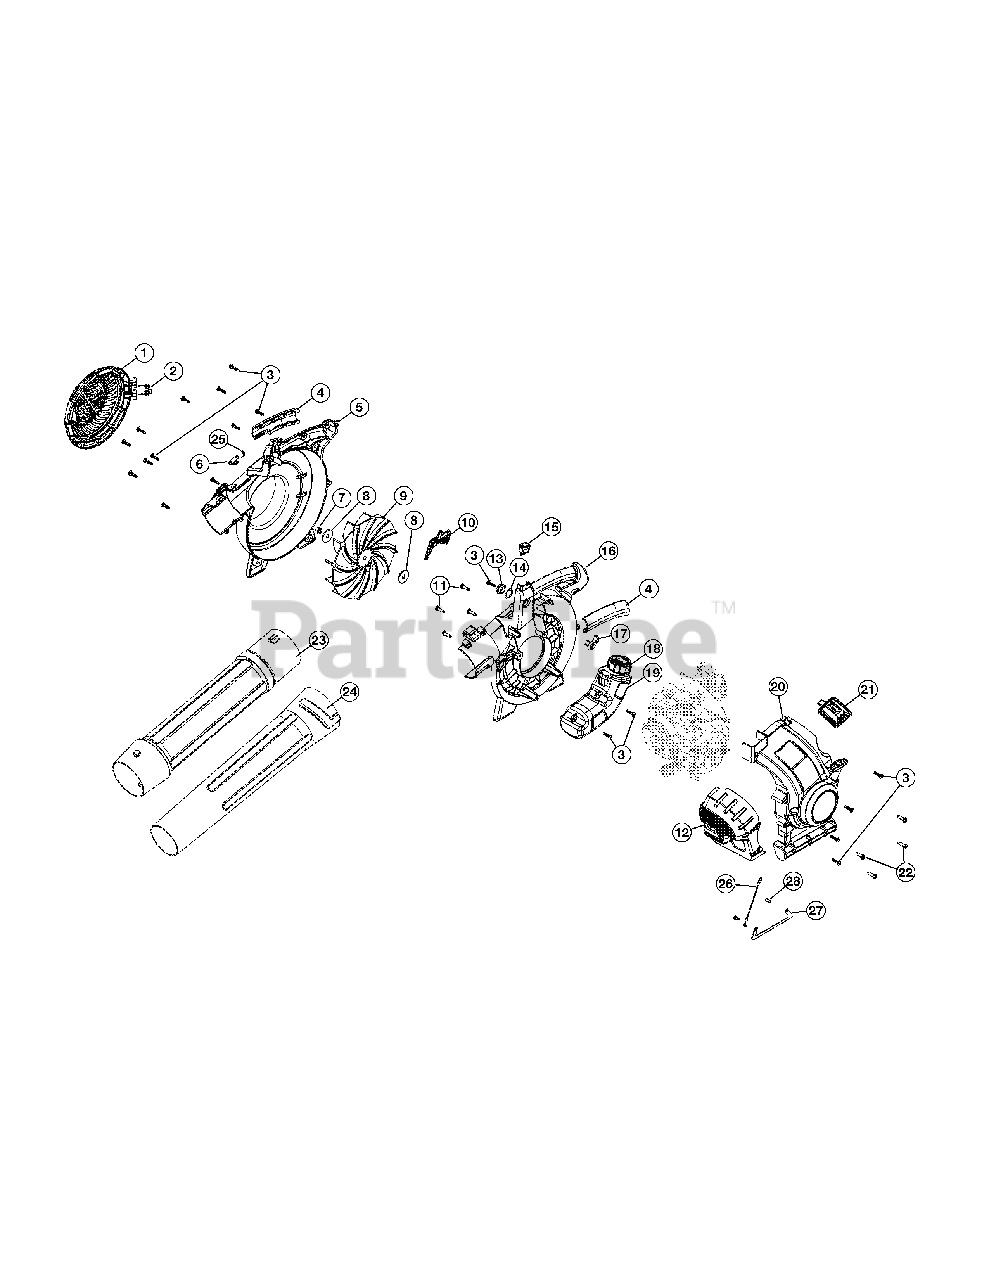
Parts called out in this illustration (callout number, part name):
1	Intake Cover
4	Handle Grips
5	Impeller Housing (Incl. Ref No. 4)
6	Latch Tube
10	Throttle Trigger
11	Screw
12	Muffler Cover (Incl. Ref No. 3)
13	Inner Trigger Lock
14	Wavey Washer
16	Impeller Housing (Incl. Ref No. 4)
17	Outer Trigger Lock
19	Fuel Tank Assembly (Incl. Ref No. 18)
20	Engine Cover Assembly (Incl. Ref No. 3, 21 & 22)
21	Spark Plug Cover
23	Upper Tube
24	Lower Tube
25	Latch Spring
26	Wire Ground
27	Strap Ground
28	Screw
